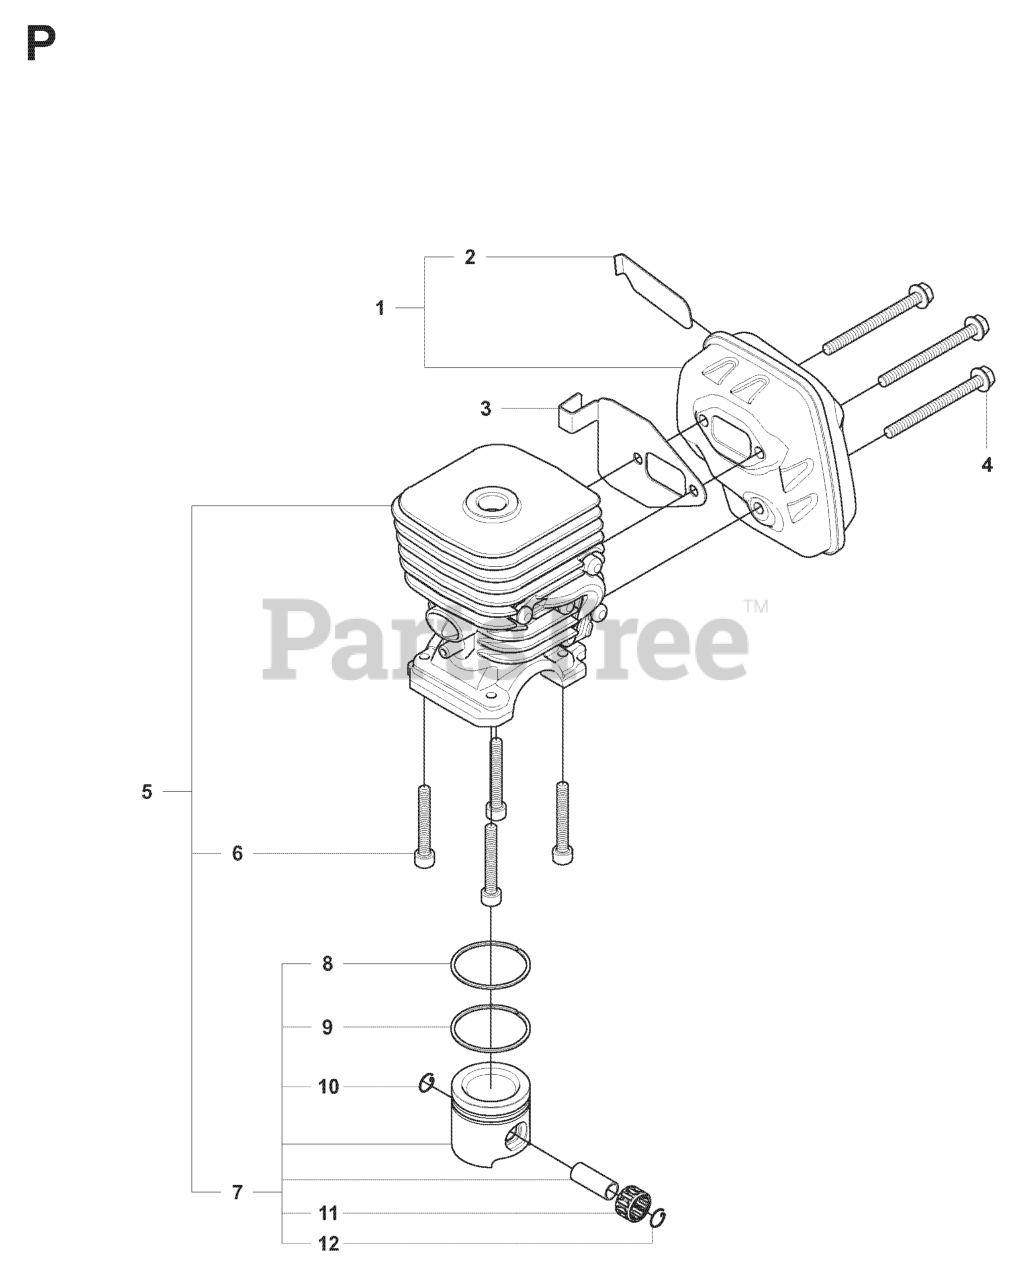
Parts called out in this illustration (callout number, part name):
1	MUFFLER KIT
2	SPARK ARRESTOR SCREEN
5	CYLINDER COMPL
6	SCREW
8	PISTON RING
9	PISTON RING
